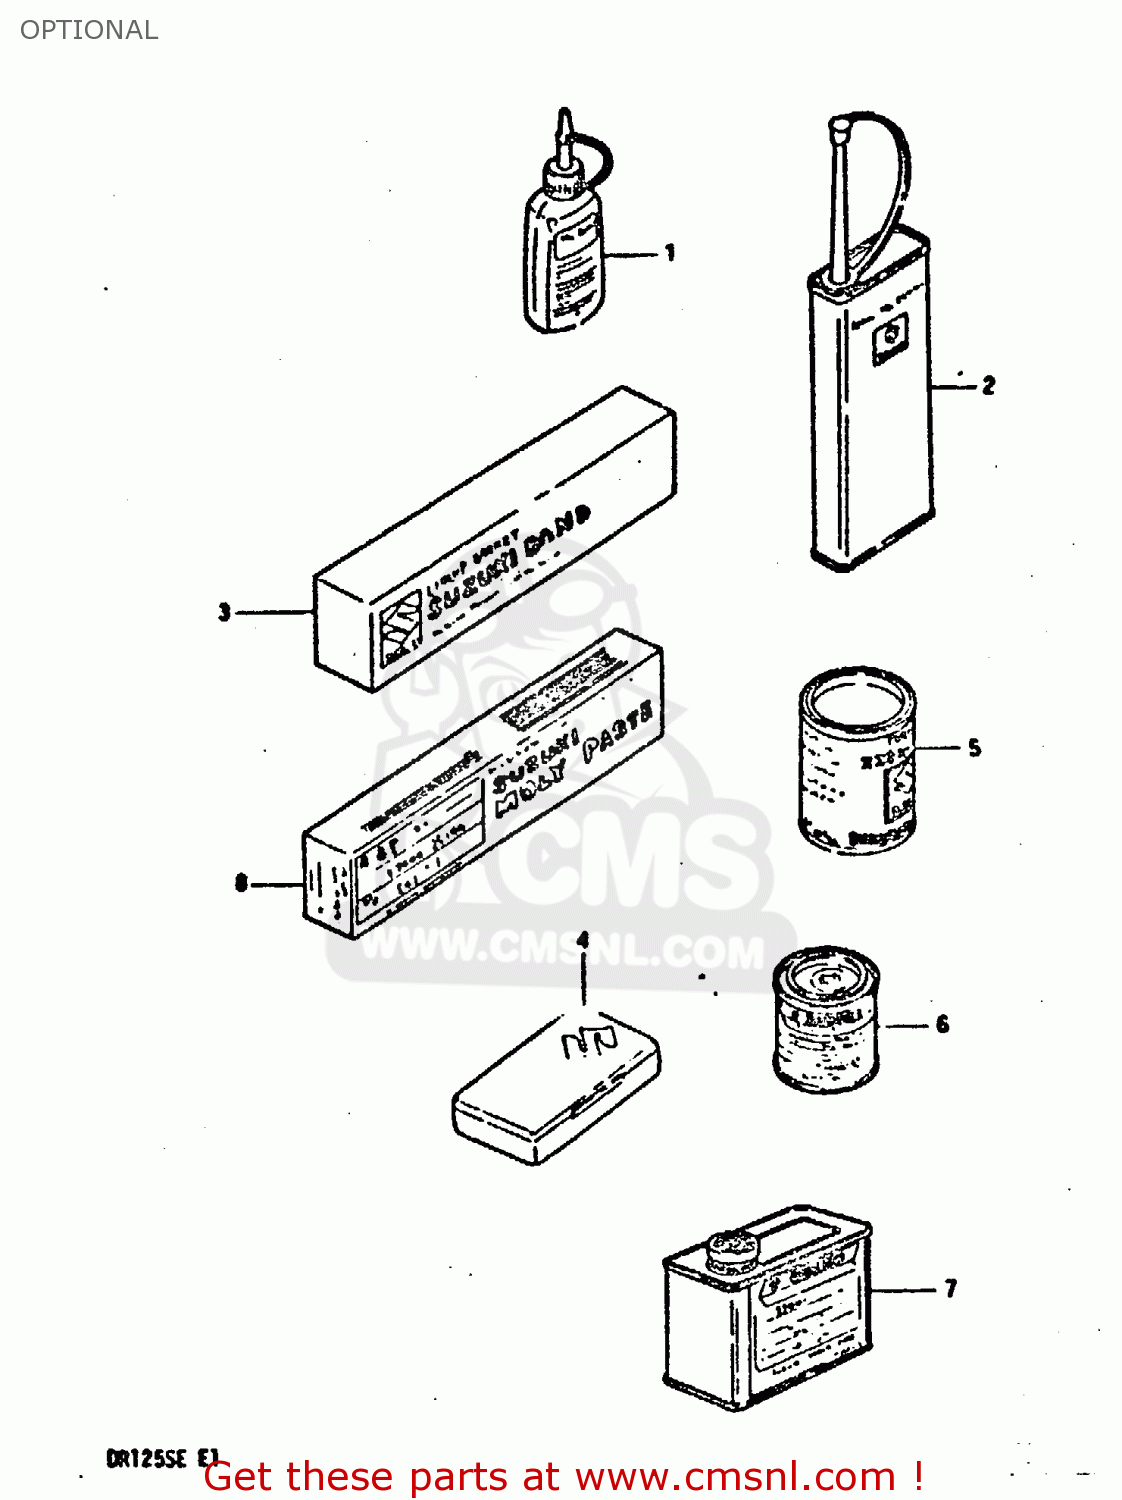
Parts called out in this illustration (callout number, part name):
1	THREAD LOCK NO.1342
2	THREAD LOCK NO.1401 CLEAR 200G
3	LIQUID GSKT NO.1207B 100G BLK
4	TUBE REPARING TOOL
5	GREASE(C)EP2 LITHIUM 150G
6	PAINT,BLACK
7	PAINT (BLACK)
8	SUZUKI MOLY PASTE
